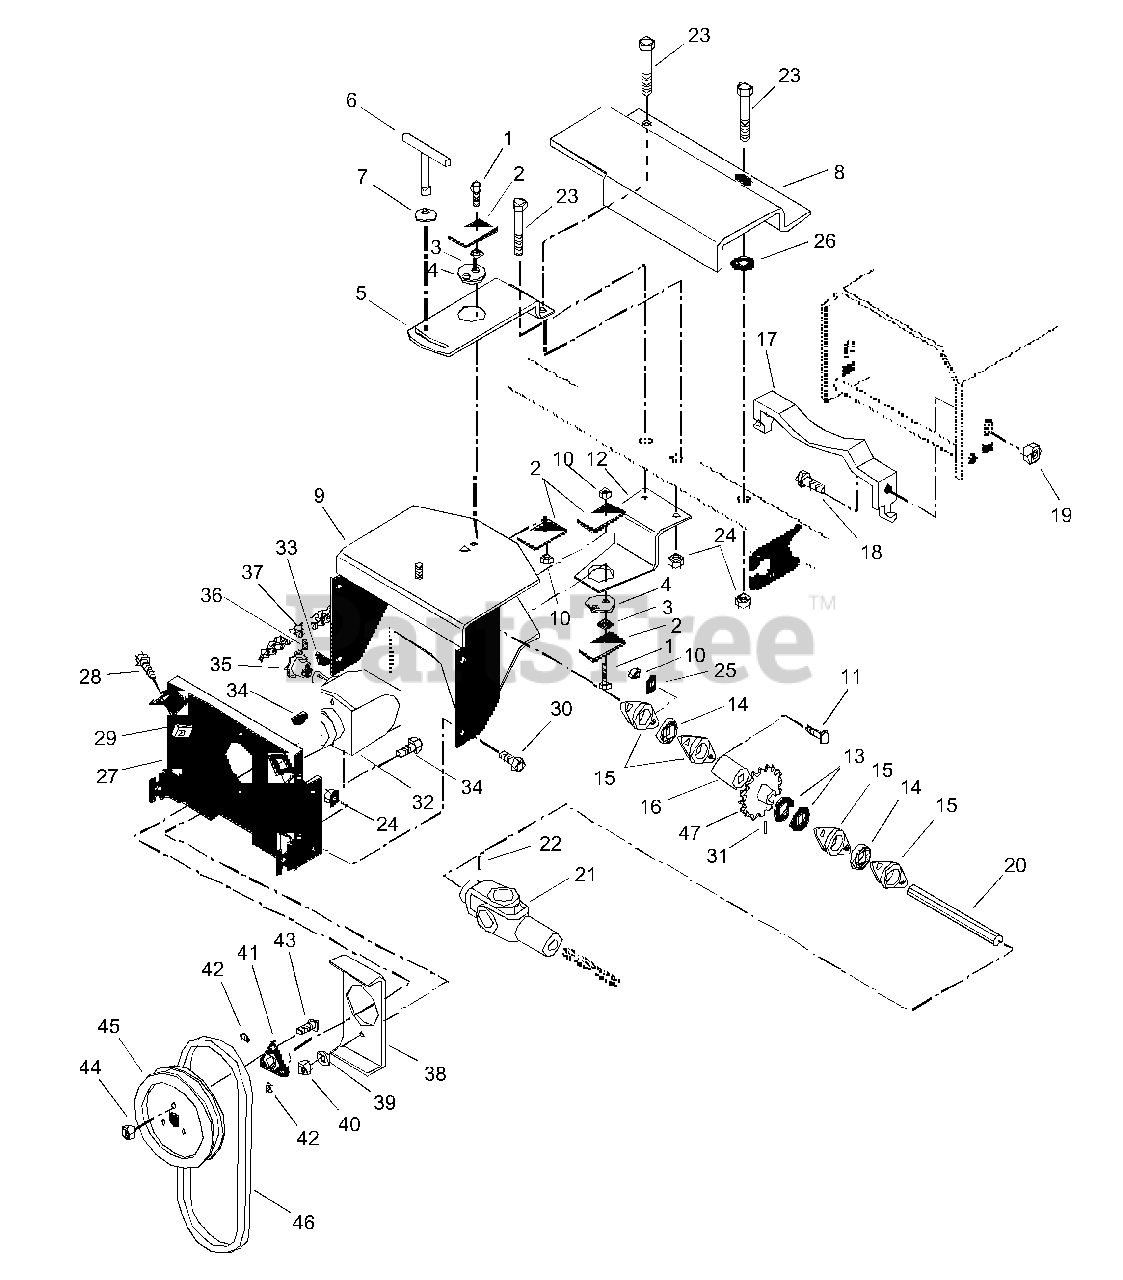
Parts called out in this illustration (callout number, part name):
1	@BLT-HEX .31-18X1.25 GR5 YWZC
2	RETAINER
3	@WSHR-LK-EXT.326X.599X.031YWZC
4	PIVOT CENTER
5	PLATE, TOP MOUNT
6	T-LOCK HANDLE
7	WASHER, CUPPED SERRATED, .375
8	GUARD, SHAFT
9	ADAPTER FRAME
10	@NUT-LK-CTR .31-18 YWZC
11	@BLT-RDHDSQNK .31-18X.75 G5YZ
12	PLATE, BOTTOM MOUNT
13	WSHR-FL-STL 1.015X1.500X.125
14	BRG-BALL .884HEXX52MMX1.07
15	BEARING FLANGE
16	SPACER 1.006X1.307X.500
17	BELT RETAINER
18	@BLT-HEX .25-20X.50 GR5 YWZC
19	@NUT-LK-CTR .25-20 YWZC
21	JOINT, UNIVERSAL
22	PIN-ROLL .188X1.50
23	@BLT-HEX .38-16X3.25 GR5 YWZC
24	@NUT-LK-CTR .38-16 YWZC
25	@WSHR-FL-STL.38X.875X.083 YWZC
26	WSHR-FL-STL .390X.88X.18 YWZC
27	MOUNTING PLATE
28	BLT-SERHFWH .38-16X.75 YWZC
29	NUT-RETNR .38-16 TINRMAN
30	@BLT-HEX .38-16X.75 GR5 YWZC
31	PIN-ROLL .188X1.75
32	GEAR BOX ASSEMBLY
33	KEY-WDRF .188X.75X.313 SAE 9
34	@BLT-HEX .38-16X1.25 GR5 YWZC
35	SPROCKET
36	SCR-SET .25-20X.38 SKHCUPNL OH
37	CHAIN
38	STIFFENER PLATE
39	@WSHR-LK .38X.094 REG YWZC
40	@NUT-HEX .38-16 YWZC
41	HUB ASSEMBLY
42	SCR-SET .31-18X.38 SKHCUPDL
43	BLT-SERRDHD SL .31-18X.75 YZ
44	@NUT-SPNLK-FLG .312-18 YWZC
45	PLY-V 9.0 X 1.25 3BLT
46	V-BELT, 4L-RAW EDGE
47	SPROCKET
